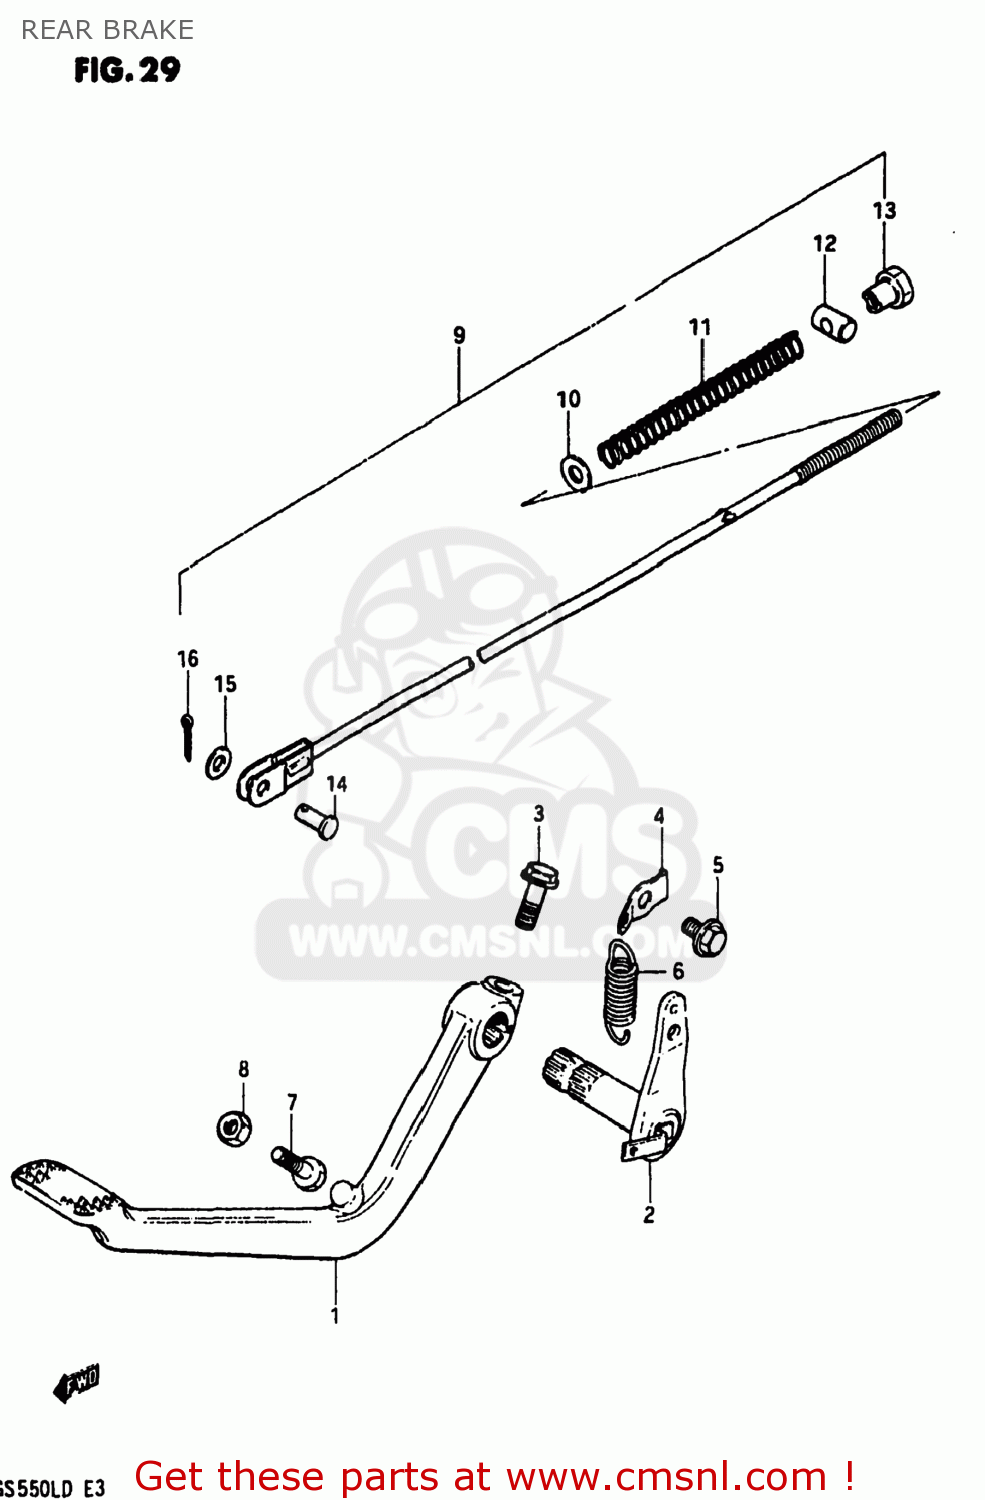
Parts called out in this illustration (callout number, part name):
1	PEDAL,BRAKE
2	ARM,BRAKE PEDAL
3	BOLT
4	PLATE.SPRING
5	BOLT
6	SPRING
7	BOLT
8	NUT
9	ROD ASSEMBLY,REAR BRAKE
10	WASHER
11	SPRING
12	PIN
13	NUT (6MM)
14	PIN(L:13.5)
15	WASHER
16	PIN 20X20
